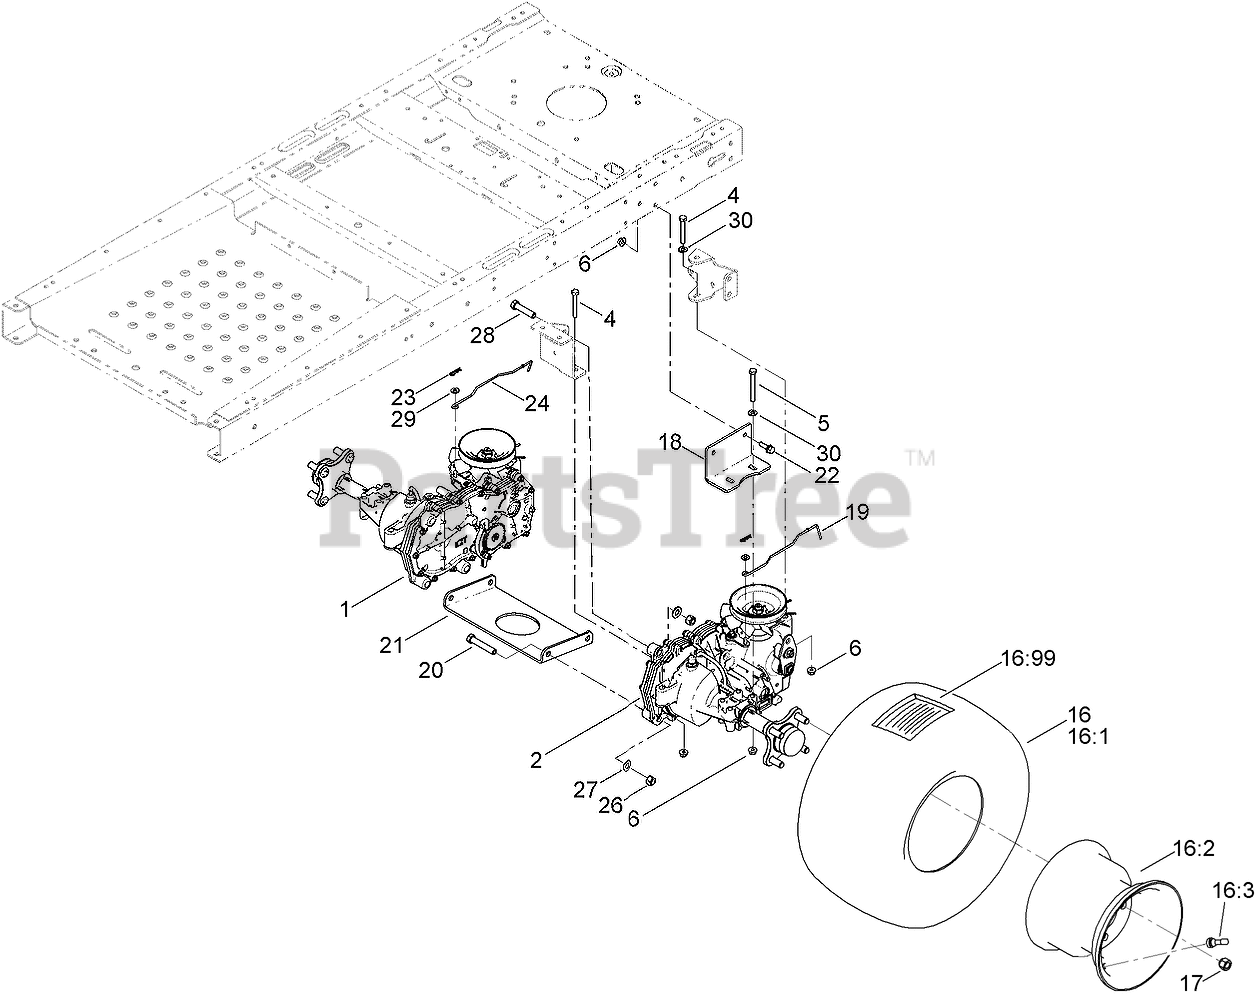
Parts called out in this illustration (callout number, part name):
1	RH HYDRO TRANSAXLE ASM
2	LH HYDRO TRANSAXLE ASM
4	SCREW-HH
5	SCREW-HH
6	NUT-HF, NI
16	4 PLY WHEEL AND TIRE ASM
16:1	TIRE-4 PLY
16:3	STEM-VALVE
16:99	TUBE-TIRE
17	NUT-LUG
18	MOUNT-HYDRO
19	ROD-BYPASS, LH
20	SCREW-HH
21	PLATE-CROSS, HYDRO
22	SCREW-HHF
23	PIN-COTTER
24	ROD-BYPASS, RH
26	NUT-LOCK, NI
27	WASHER-FLAT
28	SCREW-HH
29	WASHER
30	WASHER-PLAIN
